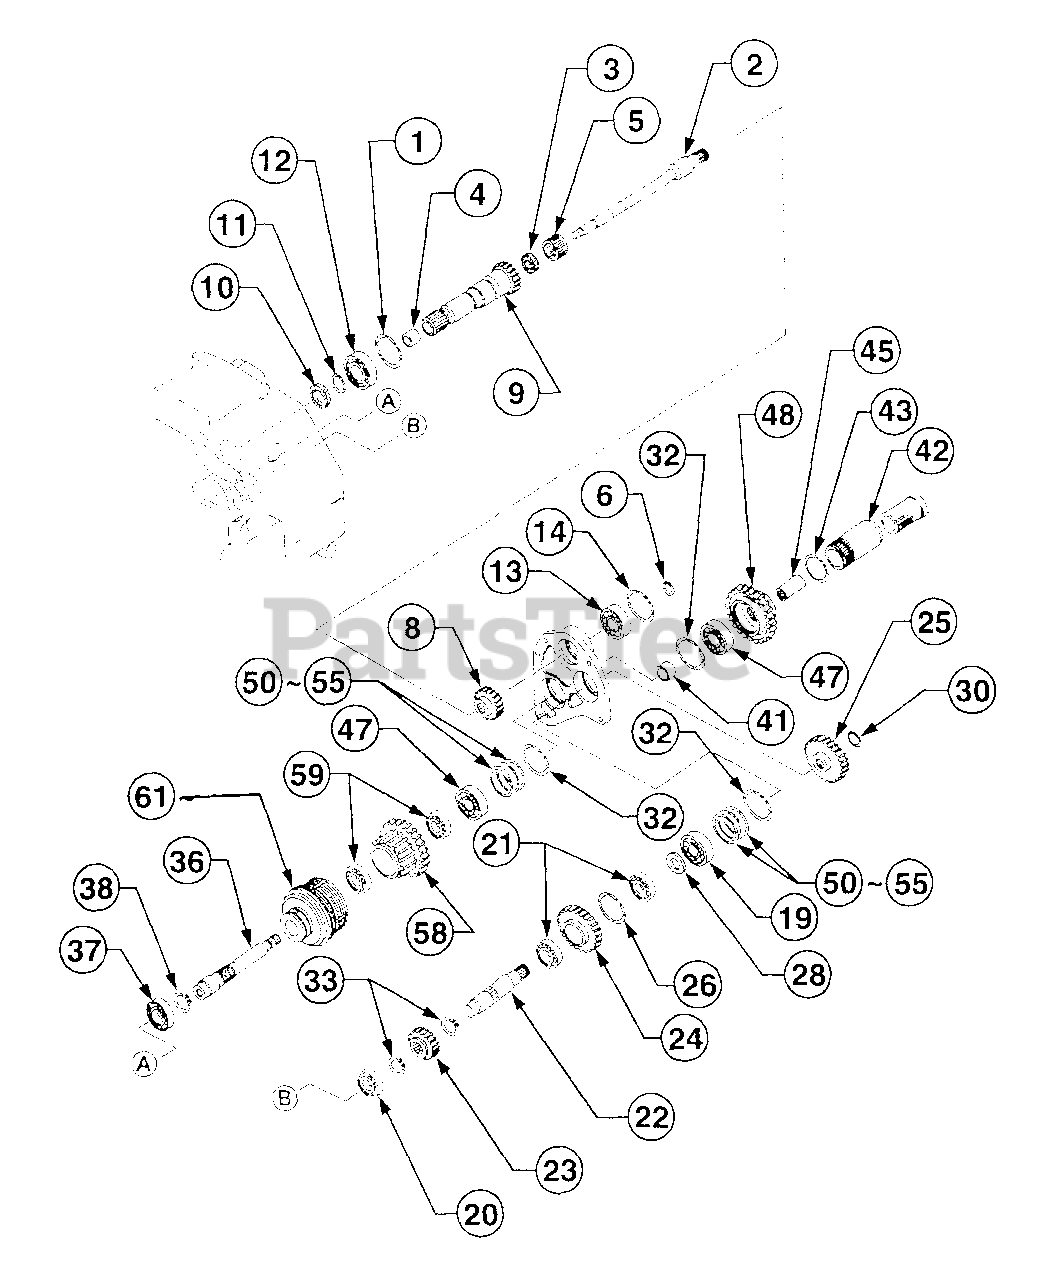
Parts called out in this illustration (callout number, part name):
5	Bearing, Needle
9	Shaft Drive A
12	Bearing, Ball
13	Bearing, Ball
19	Bearing, Ball
20	Bearing, Ball
21	Bearing, Ball
30	C-Ring
37	Bearing, Ball
45	Joint, Front
47	Bearing, Ball
50	Liner, t=0.15
59	Bearing, Ball
61	PTO Clutch Ass'y.
